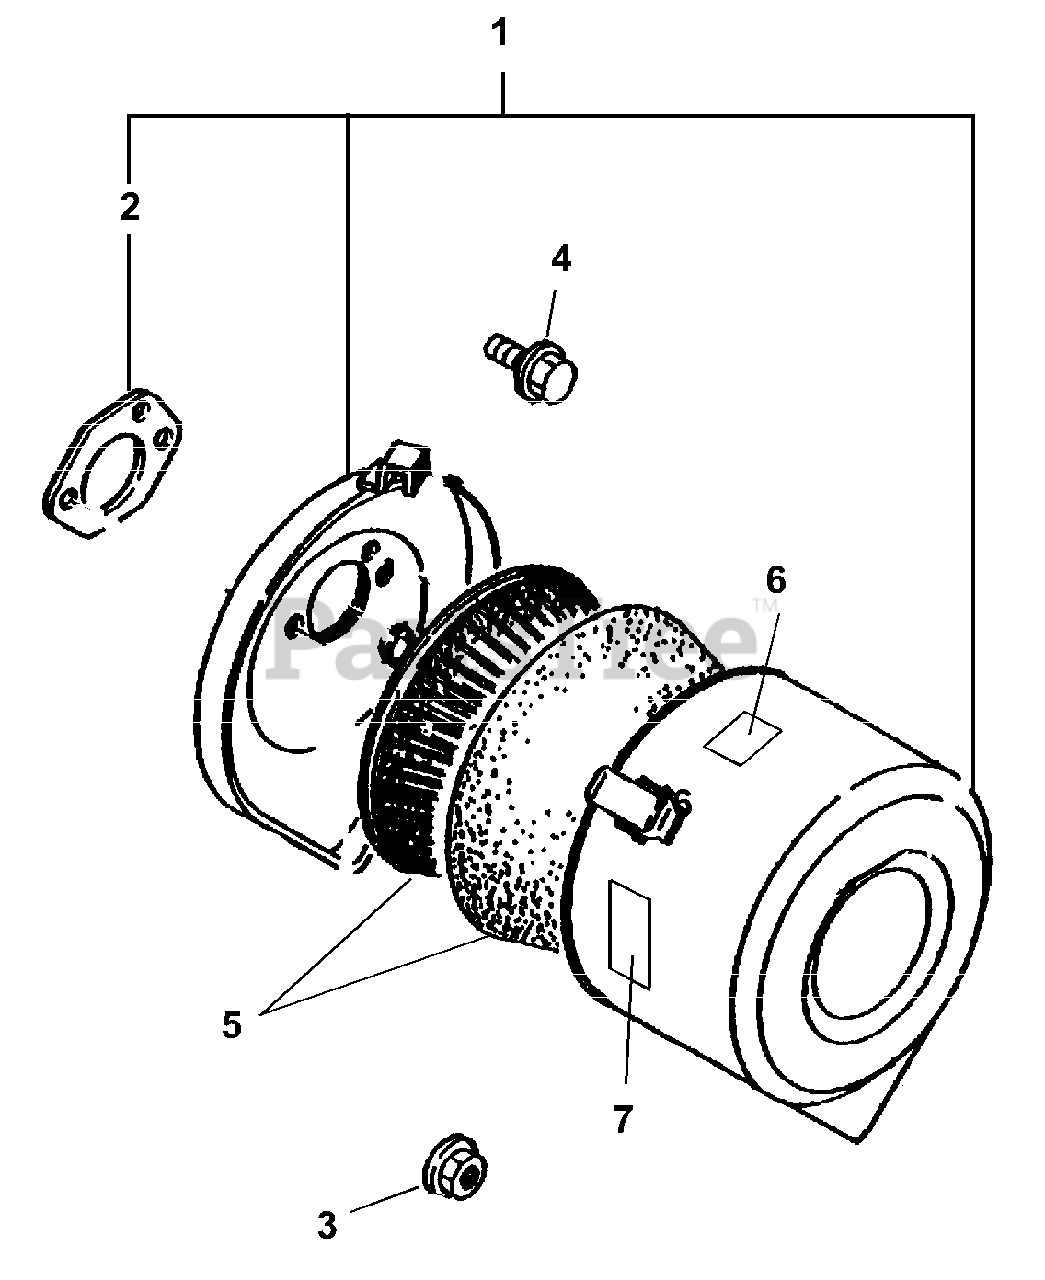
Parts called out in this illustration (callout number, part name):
1	Air Cleaner AY
2	Gasket
3	Flange Nut
4	Bolt and washer
5	Element set
6	Choke Label
7	Label, cleaner
